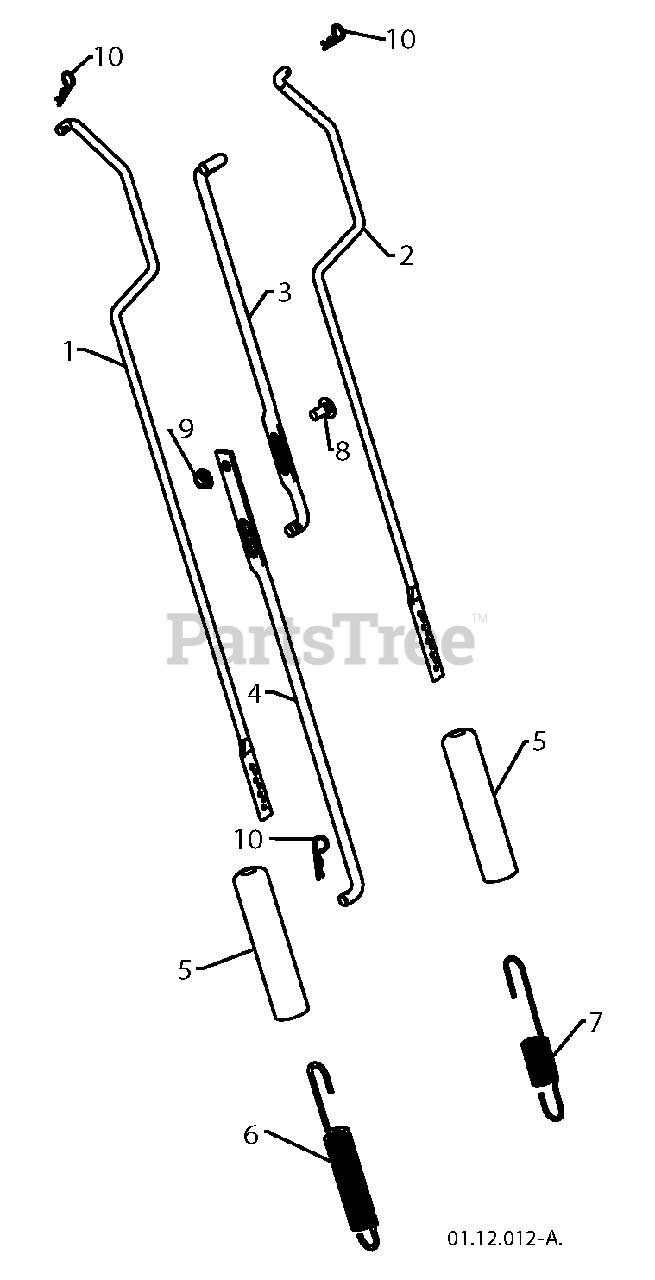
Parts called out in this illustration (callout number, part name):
1	ROD.IMPELLER.CONTROL.HYD.II.SN
2	ROD.TRACTION.CONTROL.SNOW
3	ROD.SHIFTER.TOP.HYD.SNOW
4	ROD, LOWER, SPEED CONTROL
5	SLEEVE, SPRING
6	SPRING.CONTROL.ROD.SNOW
7	SPRING.TRACTION.ROD.SNOW
8	BOLT
9	NUT.FLANGE.5/16
10	SPRING RETAINER
